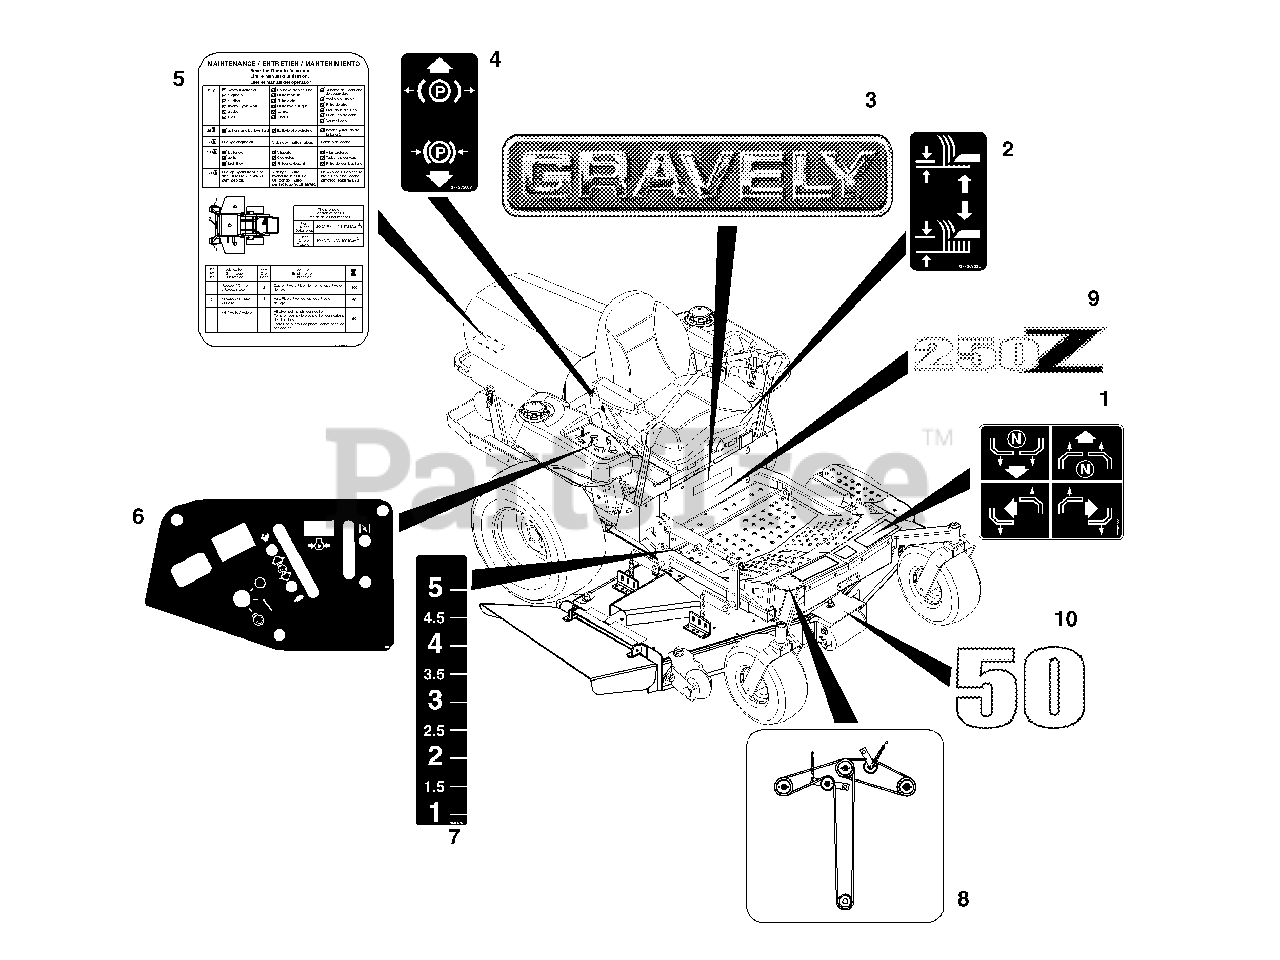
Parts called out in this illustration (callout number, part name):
1	Decal-Instructional Steering
2	Decal, Lift Lever
3	Decal, 15" Gravely Logo
4	Decal, Parking Brake Lever
5	Decal, Service Instructions
6	Decal, Control Panel
6	Decal, Control Panel-EFI
7	Decal, Height of Cut
8	Decal, Belt Diagram
9	Decal, Logo- Gravely 250Z
9	Decal, PM-260Z
9	Decal, PM-272Z
10	Decal, 50
10	Decal, 60
10	Decal, 72
